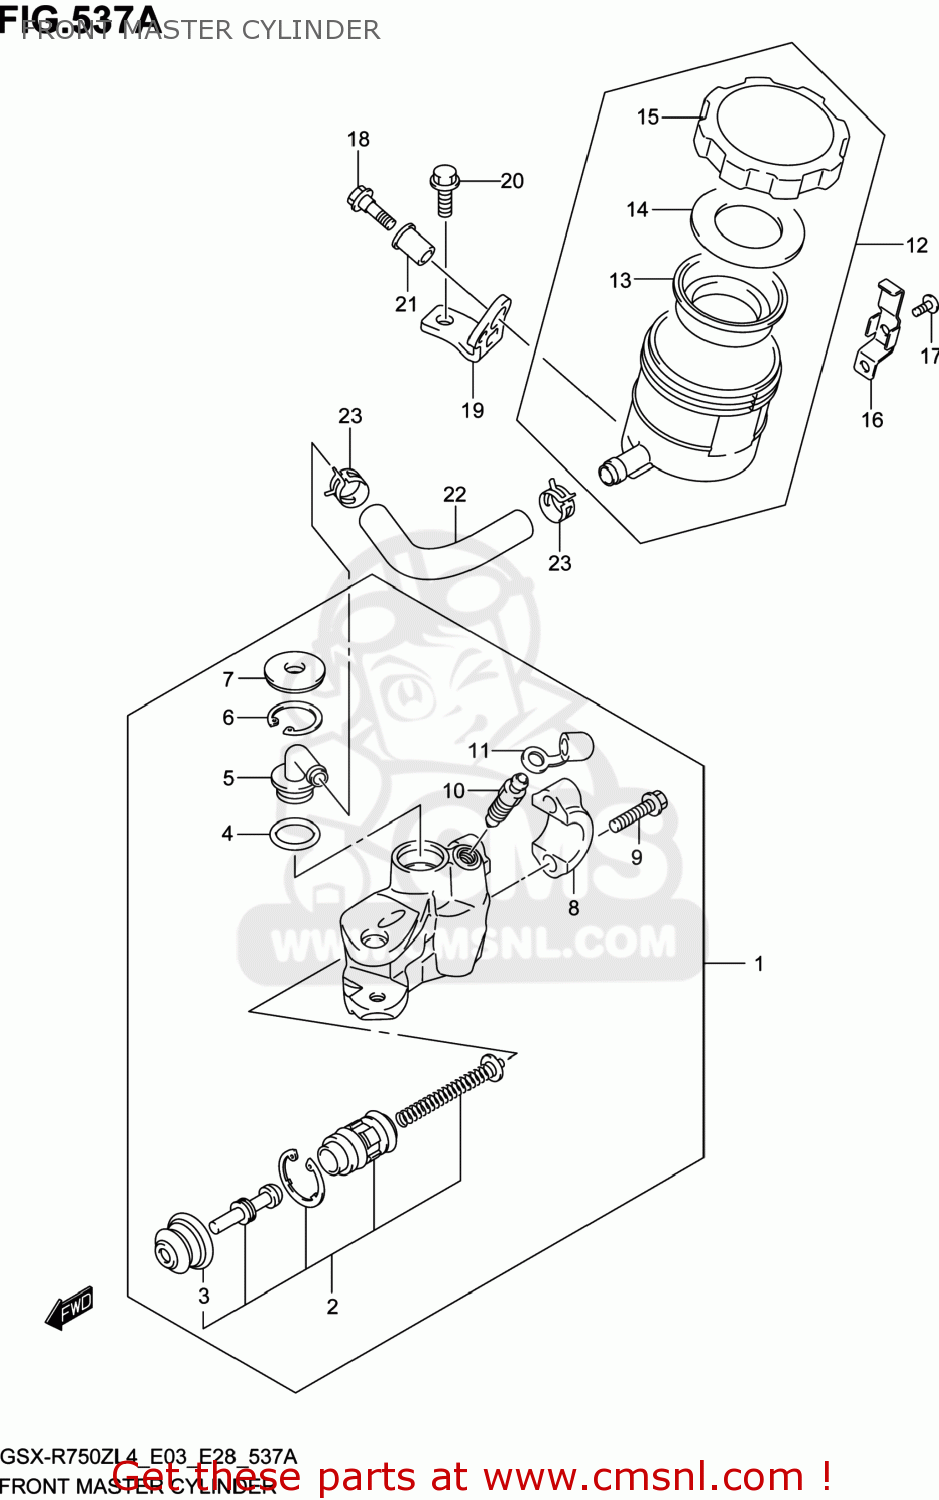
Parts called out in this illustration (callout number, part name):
1	CYLINDER ASSY,FRONT MASTER
2	PISTON & CUP S
3	BOOT
4	O RING
5	CONNECTOR
6	CIRCLIP
7	COVER,DUST
8	HOLDER
9	BOLT(6X22)
10	BLEEDER
11	CAP,BLEEDER
12	TANK ASSY,RESERVOIR
13	DIAPHRAGM
14	PLATE,DIAPHRAGM
15	CAP
16	PLATE,RESERVOIR TANK CAP
17	SCREW
18	BOLT(5X17)
19	BRACKET,FR RESERVOIR TANK
20	BOLT
21	NUT
22	HOSE,FRONT RESERVOIR TANK
23	CLAMP,RESERVOIR TANK FR
